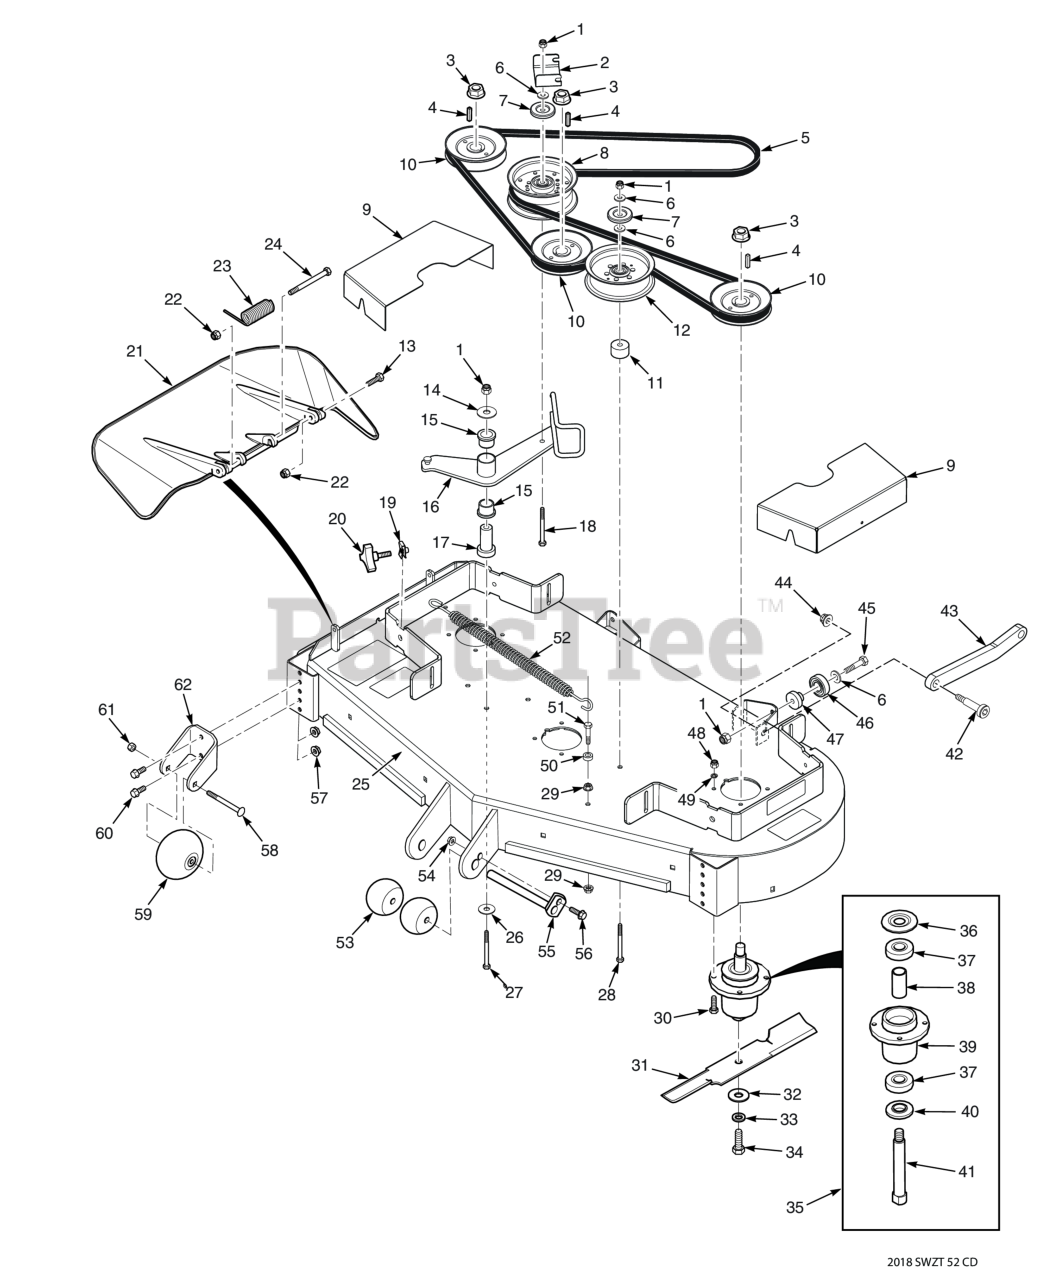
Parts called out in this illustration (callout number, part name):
1	HEX NUT, ELASTIC STOP LOCK, 3/8-16
2	Bracket, Belt Guide
3	Nut, 3/4-16 Spriral Lock
4	Key, 1/4 x 1/4 x 1.25" Pulley Mtg.
5	Belt, Cutter Deck
6	Flatwasher, 3/8 (.391 x .938 x .105 HD) Grade 8
7	Quick Pin, 5/16" Dia.
8	Pulley, Idler 5" Dia.
9	Belt Cover
10	Pulley, 5.73" OD - 25mm Bore
11	Spacer, Idler Pulley
12	Pulley, 5" Idler
13	Bolt, Hex Head 5/16-18 x 1-1/2" - Front
14	Flatwasher, 3/8-.406 x 1-1-1/2 x 7 Gauge
15	Bearing, Plastic
16	Idler Arm (incl. item #15)
17	Pivot, Idler
18	Capscrew, Hex Head 3/8-16 x 3.25"
19	U-Nut, 3/8-16
20	Knob, w/stud 3/8-16 x 1-1/4"
21	Discharge Chute Assy. SFZ52
22	HEX NUT, ELASTIC STOP LOCK, 5/16-18
23	Spring, Discharge Chute
24	Bolt, 5/16-18 x 4-3/4" Hex Head
25	Cutter Deck w/Decals, SWZT52H
26	Flatwasher, 3/8-.406 x 2.25" x .1875
27	Capscrew, Hex Head 3/8-16 x 3-3/4"
28	Bolt, Hex Head, 3/8-16 x 3-1/2"
29	NUT, 3/8-16 SERRATED FLANGE HEX HEAD
30	Bolt, Hex Head 5/16-18 x 1-1/2" Grade 8
31	Cutter Blade, 18" (52V)
32	Flatwasher, 5/8-.688 x 1-3/4 x .134 HD
33	Lockwasher, 5/8" Spring
34	Bolt, Hex Head 5/8-11 x 1-1/2"
35	Spindle Assembly
36	Debris Shield
37	Bearing
38	Spacer, Bearing
39	Spindle Housing Assembly
40	Protector, Bearing
41	Shaft, Spindle
42	Bolt, Shoulder 1/2 x 3/8-16 x 2-3/4"
43	Pusharm
44	Nut, Flange Elastic Stop Nut, 3/8-16
45	Bolt, Hex Head 3/8-16 x 1-3/4" (Kohler EFI)
46	Bearing
47	Spacer, Bearing
48	Lock Nut, 5/16-18 Elastic Stop Grade 8
49	Lockwasher, 5/16 (.317 x .586 x .078) Helical Spring
50	SPACER, IDLER
51	Bolt, Hex Head 3/8-16 x 1-1/2" Grade 8 Black
52	Spring, L.H. Deck Drive
53	Wheel, Anti-Scalp
54	Nut, Serrated Flange 5/16-18 (Right Front Engine Mounting, Briggs and Kohler Only)
55	Shaft Weldment, Guide Roller
56	Bolt, Heax Head 5/16-18 x 1" (48V / 52V)
57	NUT, 3/8-16 SERRATED FLANGE HEX HEAD
58	Bolt, Hex Head 3/8-16 x 3-1/2"
59	Bolt, Carriage 3/8-16 x 4"
60	Capscrew, 3/8-16 x 1.0" Serrated Flange Hex Hd
61	Bolt, Hex Head 3/8-16 x 1" Ser. Flg.
62	Bracket, Anti-Scalp Wheel
